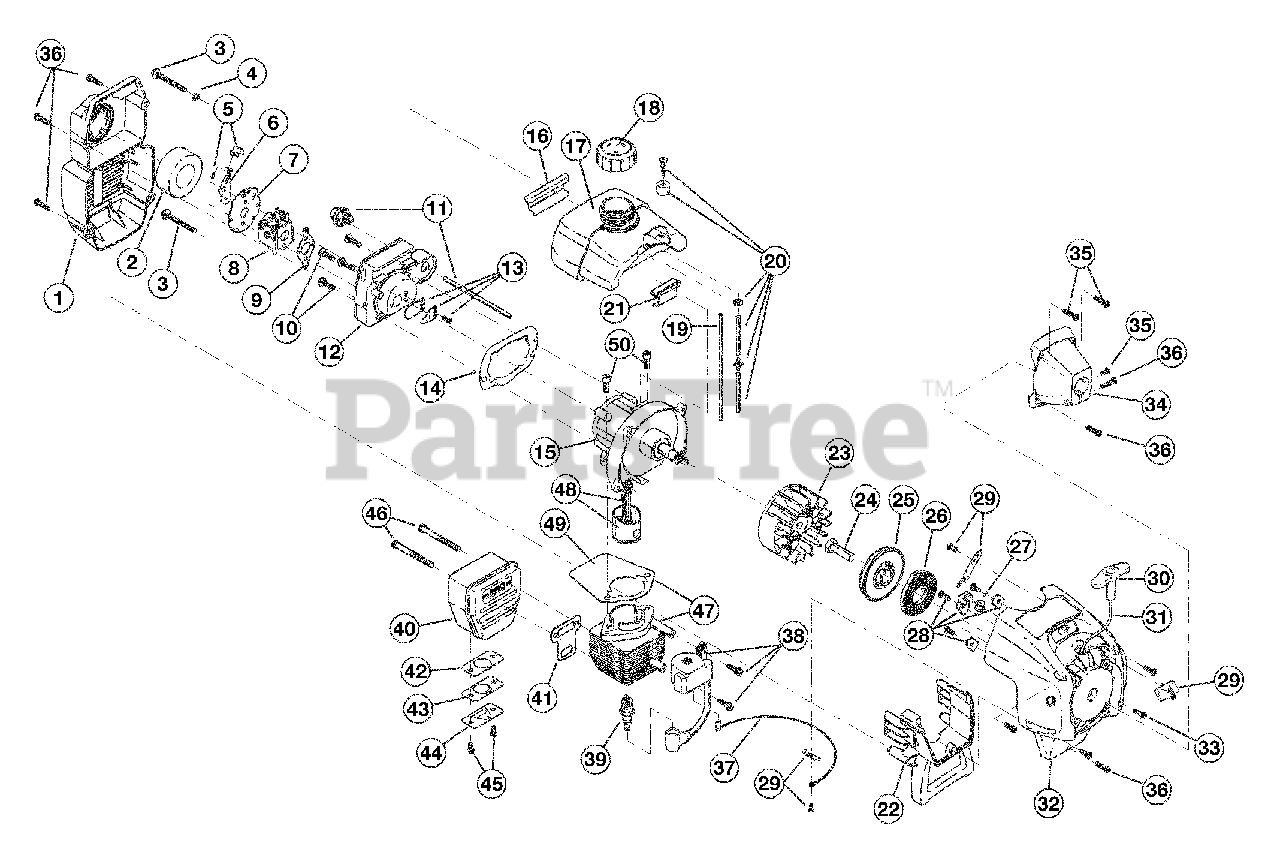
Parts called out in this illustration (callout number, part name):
1	Air Cleaner/Muffler Cover Assembly
2	Air Cleaner Filter
3	Carburetor Mounting Screw Assembly
4	Wavy Washer
5	Choke Knob and Screw
6	Choke Lever Assembly
7	Choke Plate Assembly
8	Carburetor Assembly
9	Carburetor Gasket
10	Carb Mount Screw
11	Primer Assembly
12	Carb Mount Assembly
13	Reed Assembly
14	Carburetor Mount Gasket
15	Crank Case Service Assembly
16	Rear Mounting Pad
17	Fuel Tank Assembly
18	Fuel Cap Assembly
19	Fuel Return Line
20	Fuel Line Assembly
21	Front Mounting Pad
22	Shroud Extension and Stand
23	Flywheel Assembly
25	Recoil Pulley Assembly
26	Recoil Spring
27	Rope Guide
28	Pulley Retainer Assembly
29	Switch Assembly
30	Pull Handle
32	Starter Housing Assembly
33	Housing Screw
34	Clutch Cover Assembly
35	Anti-Rotation Screw
37	Wire Lead
38	Module Assembly
39	Spark Plug
40	Muffler Assembly
41	Exhaust Gasket
42	Spark Arrestor Screen
43	Spark Arrestor Plate
44	Spark Arrestor Hood
45	Screw
46	Muffler Mounting Bolt Assembly
47	Cylinder Assembly
48	Piston and Rod Assembly
49	Cylinder Gasket
50	Cylinder Bolt
